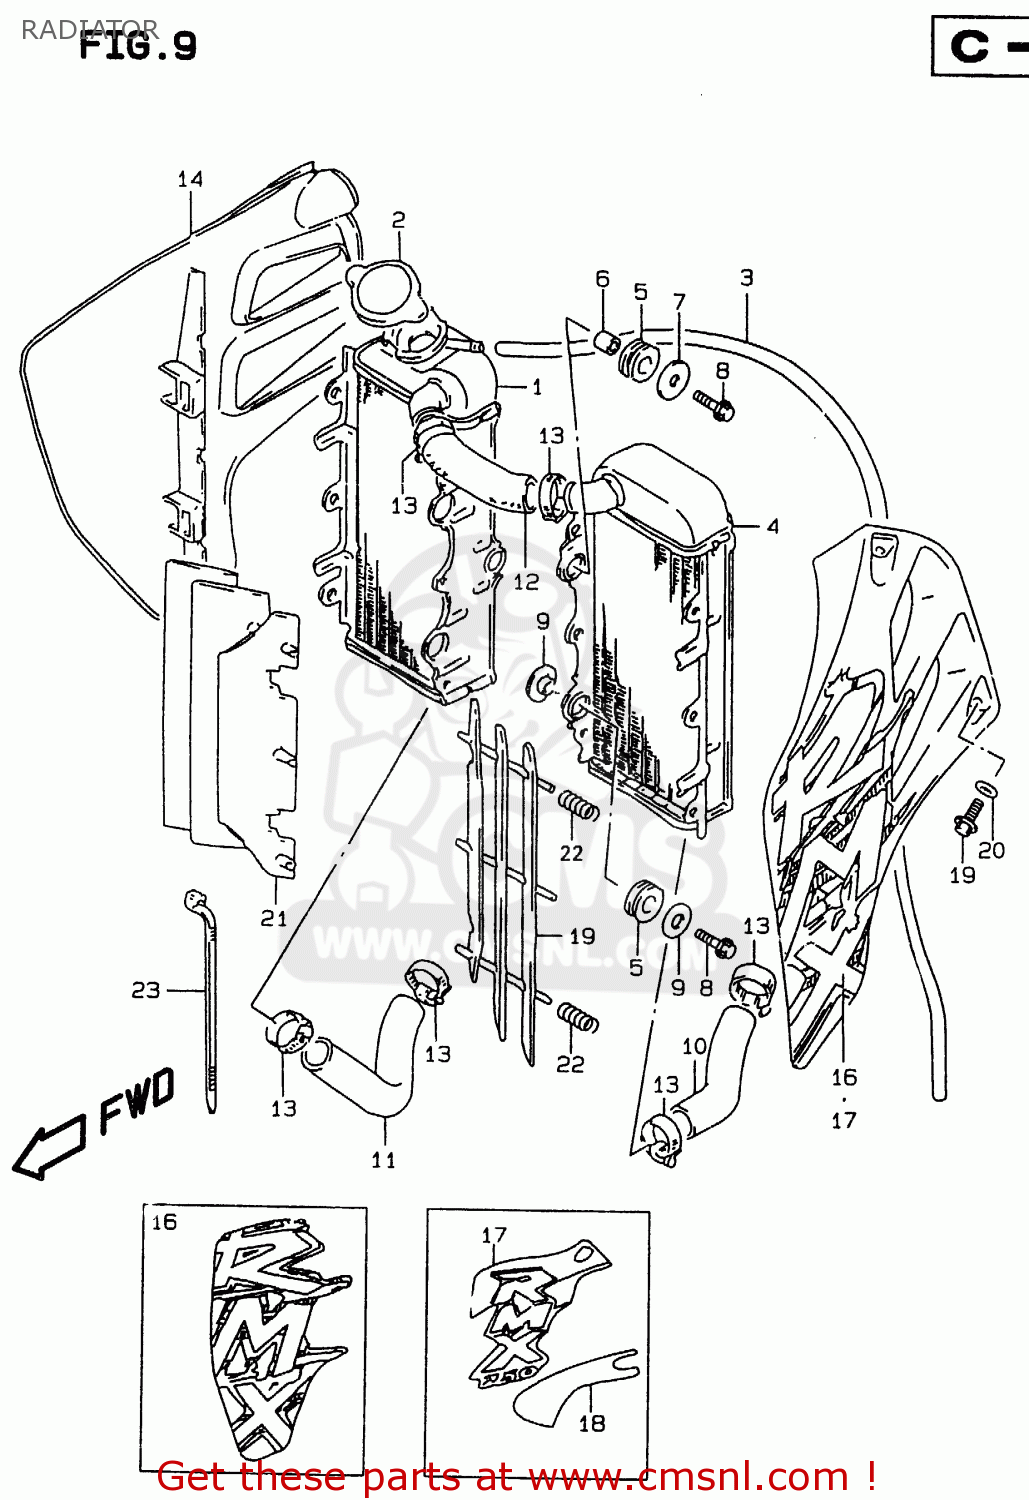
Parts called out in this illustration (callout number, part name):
1	RADIATOR,WATER,R
2	CAP,RADIATOR
3	HOSE(5X8X2000)
4	RADIATOR COMP,WATER,LEFT
5	CUSHION,RADIATOR LWR
6	SPACER(6.5X10.5X12)
7	WASHER(6.5X24X1.2)
8	SCREW
9	WASHER,RDTR SPRT
10	HOSE,RADIATOR INLET
11	HOSE,RADIATOR OUTLET
12	HOSE,RADIATOR INLET
13	CLAMP
14	COVER,RADIATOR,R
15	COVER,RADIATOR,L
16	TAPE,RADIATOR COVER,LEFT
17	EMBLEM,RADIATOR COVER
18	TAPE,RADIATOR COVER,LEFT
19	BOLT
20	WASHER
21	LOUVER,RADIATOR
22	SPRING
23	CLAMP L:165
